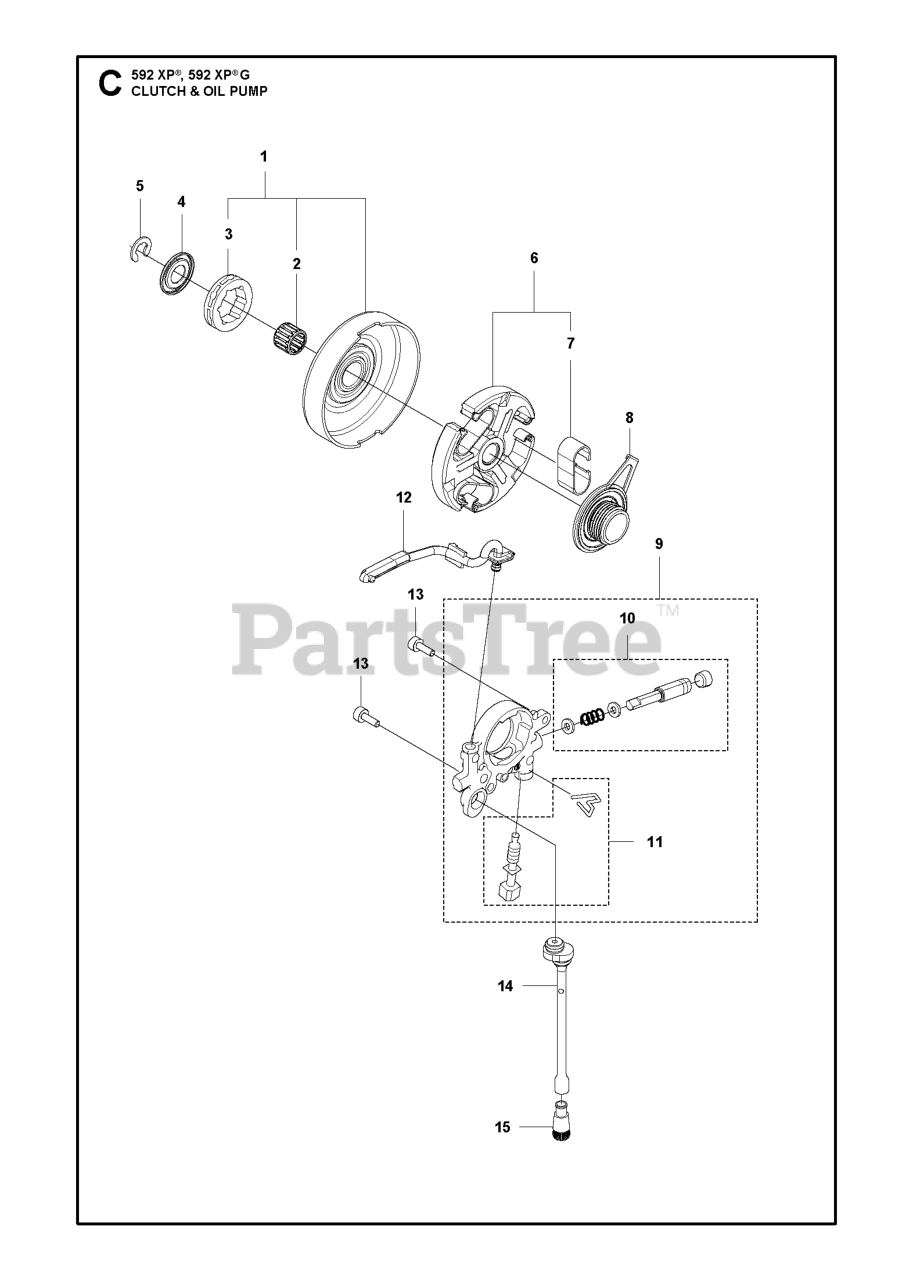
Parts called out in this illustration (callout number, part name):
1	CLUTCH DRUM ASSY KIT SPARE PAR
2	CLUTCH DRUM BEARING
3	68210 RIMSPROCKET
5	RETAINING RING
6	CLUTCH ASSY
7	CLUTCH SPRING
8	PUMP PINION ASSY
9	OIL PUMP ASSY
10	PUMP PISTON KIT H585/H592
11	OIL PUMP PIN SCREW KIT H565/H5
12	OIL PRESSURE HOSE
13	SCREW ITXSCM M4X15 T27 12.9 T
15	OIL SCREEN
